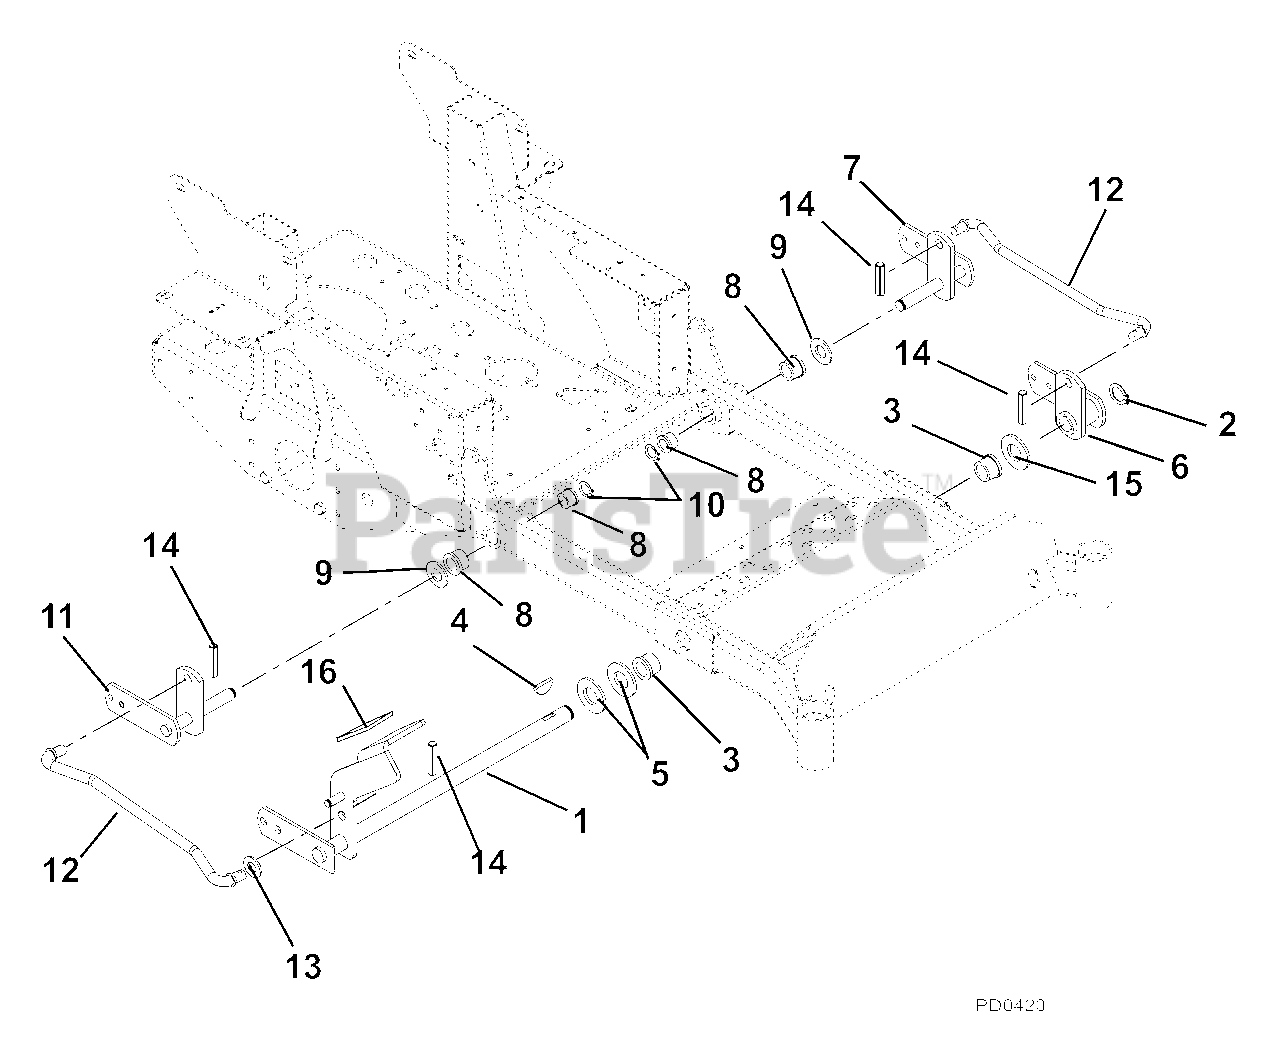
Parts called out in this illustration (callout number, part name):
1	Weldment, Lift Arm
2	Ring, Retaining External 1.00 x .078
3	Bushing, Flange Nylon 1.020 x 1.385 x .75 x 1.75
4	Key, Woodruff .25 x 1.00
5	Washer, Flat Steel 1.062 x 2.0 x .134
6	Weldment, Lift Arm-Front
7	Weldment, Lift Arm Shaft-Left Hand
8	Bushing, Flange Nylon .762 x 1.0 x .580 x 1.48
9	Washer, Hardened Steel .758 x 1.23 x .031
10	Ring, Retaining External .689 x .077
11	Weldment, Lift Arm Shaft-Right Hand
12	Rod, Lift Assist
13	Washer, Flat Steel .656 x 1.31 x .095
14	Pin, Roll .25 x 1.25 Stainless Steel
15	Washer, Hardened Thrust 1.00 x 1.55 x .03
16	Grip, Pedal
